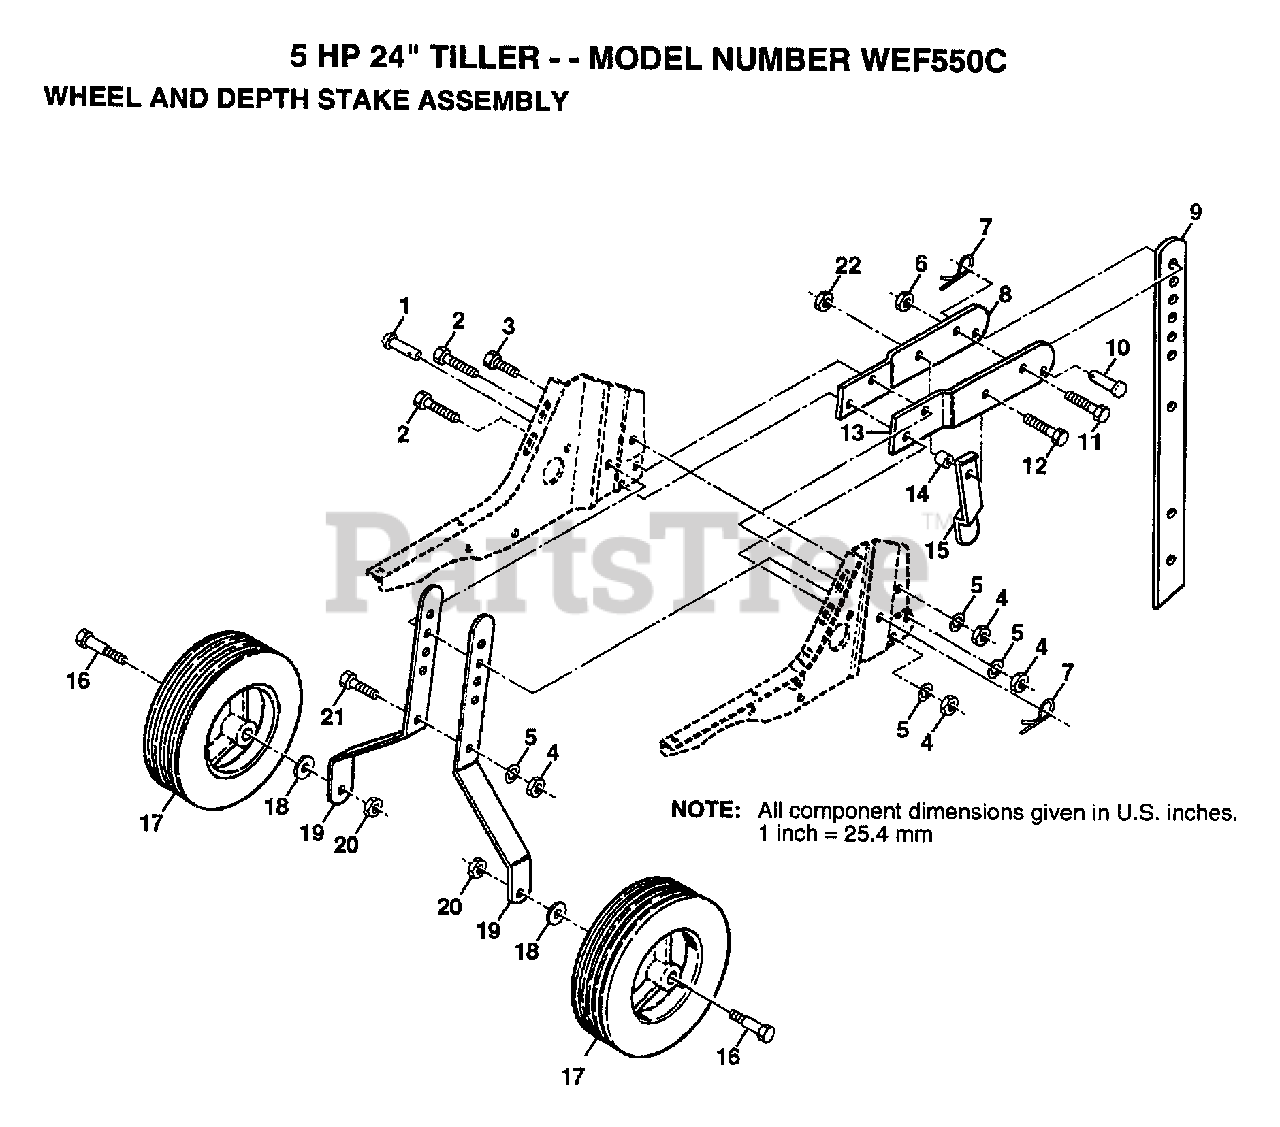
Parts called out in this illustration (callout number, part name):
1	DRILLED RIVET RT
3	BOLT
4	NUT.HEX.5/16-18
5	LOCKWASHER
6	NUT
7	SPRING.RETAINER
8	SUPPORT STAKE RH
11	BOLT
12	BOLT.HEX.5/16-1.5
13	SUPPORT STAKE LH
14	WASHER
15	STAKE SPRING TI
16	BOLT SHOULDER
17	WHEEL.8X1.75.YELL
18	WASHER
19	BRACKET.WHL.PNT.
22	NUT
